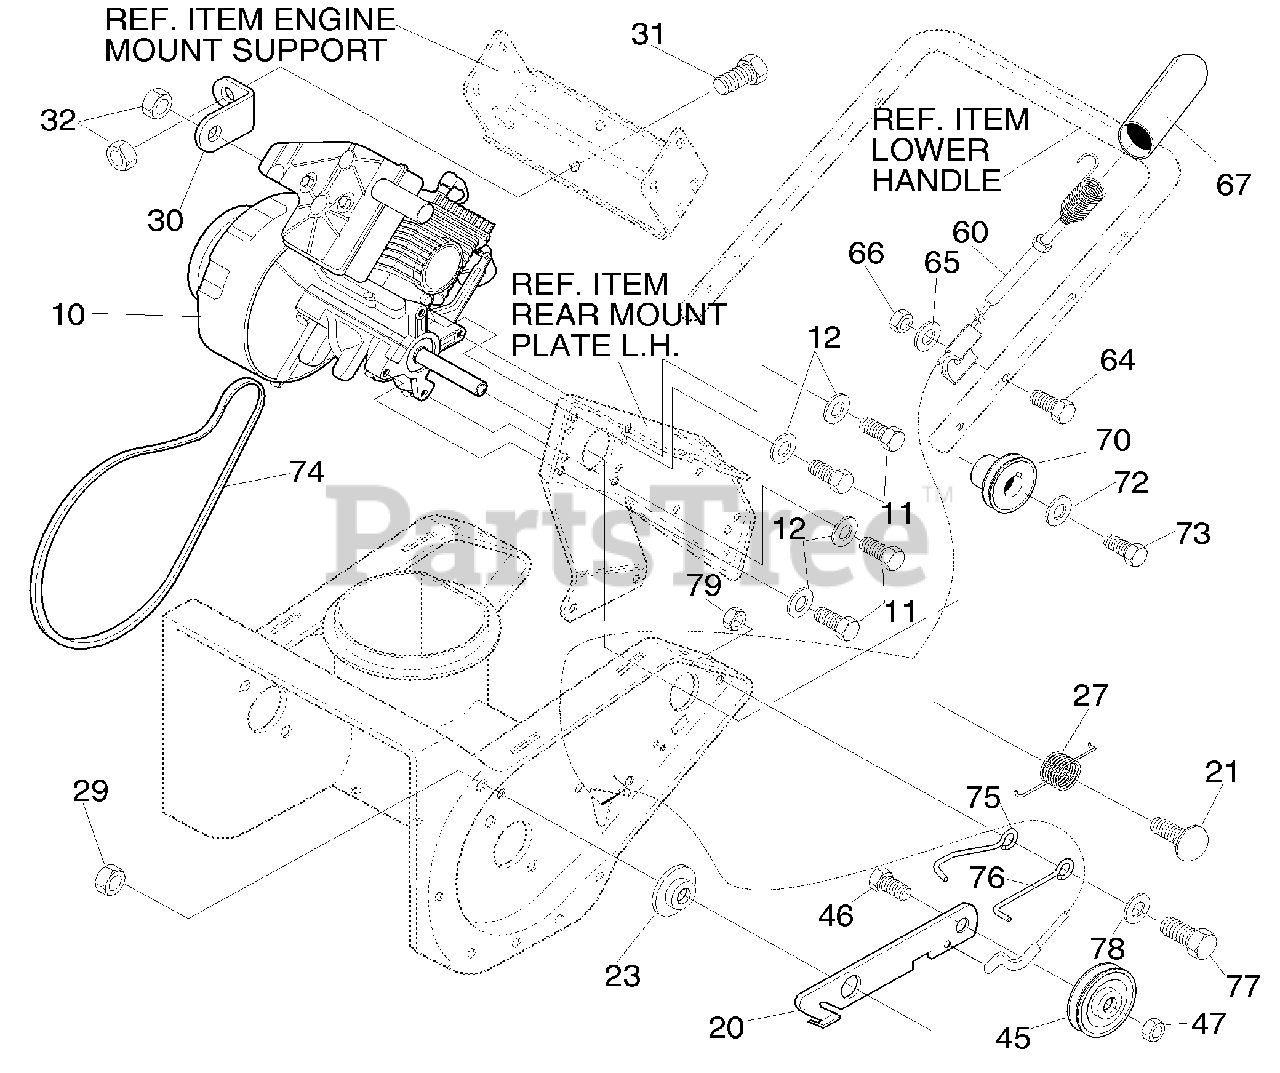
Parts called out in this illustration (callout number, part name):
10	ENGINE, 5HP 2CY (SEE ENGINE MANUAL)
11	SCREW, 5/16-18 X .75 HHC
12	WASHER, HVSPTLK
20	BRKT, IDLER ARM
21	BOLT, IDLER ARM
23	SPACER, .38 X 1.25 X .324
27	SPRING, TORSION,BRAKE
29	NUT, 3/8-16 HXCTRLKJAM
30	SUPPORT, ENGINE
31	SCREW, 5/16-18 X .50 HHC
32	NUT, 5/16-18 REGHEXCTRLK
45	PULLEY, IDLER 1.88 X .5 X .38
46	BOLT, 3/8-16 X 1.25 SPCARR
47	NUT, 3/8-16 HXCTRLKJAM
60	CABLE, DRIVE CONTROL
64	SCREW, 1/4-20 X 1.50 HHC
65	FLATWASHER .281 X .63 X .065
66	NUT, 1/4-20 REGHEXCTRLK
67	COVER, CABLE SPRING
70	PULLEY HALF, 3L 2.00
72	FLATWASHER .333 X .87 X .119
73	SCREW, 5/16-24 X .88
74	BELT, V3L X 35, .048 D
75	GUIDE, BELT .38 ID X 2.66
76	GUIDE, BELT .38 ID X 3.30 OFF
77	SCREW, 3/8-16 X 1.00 HHC
78	FLATWASHER .406 X .81 X .065
79	NUT, 3/8-16 REGMXCTRLK
